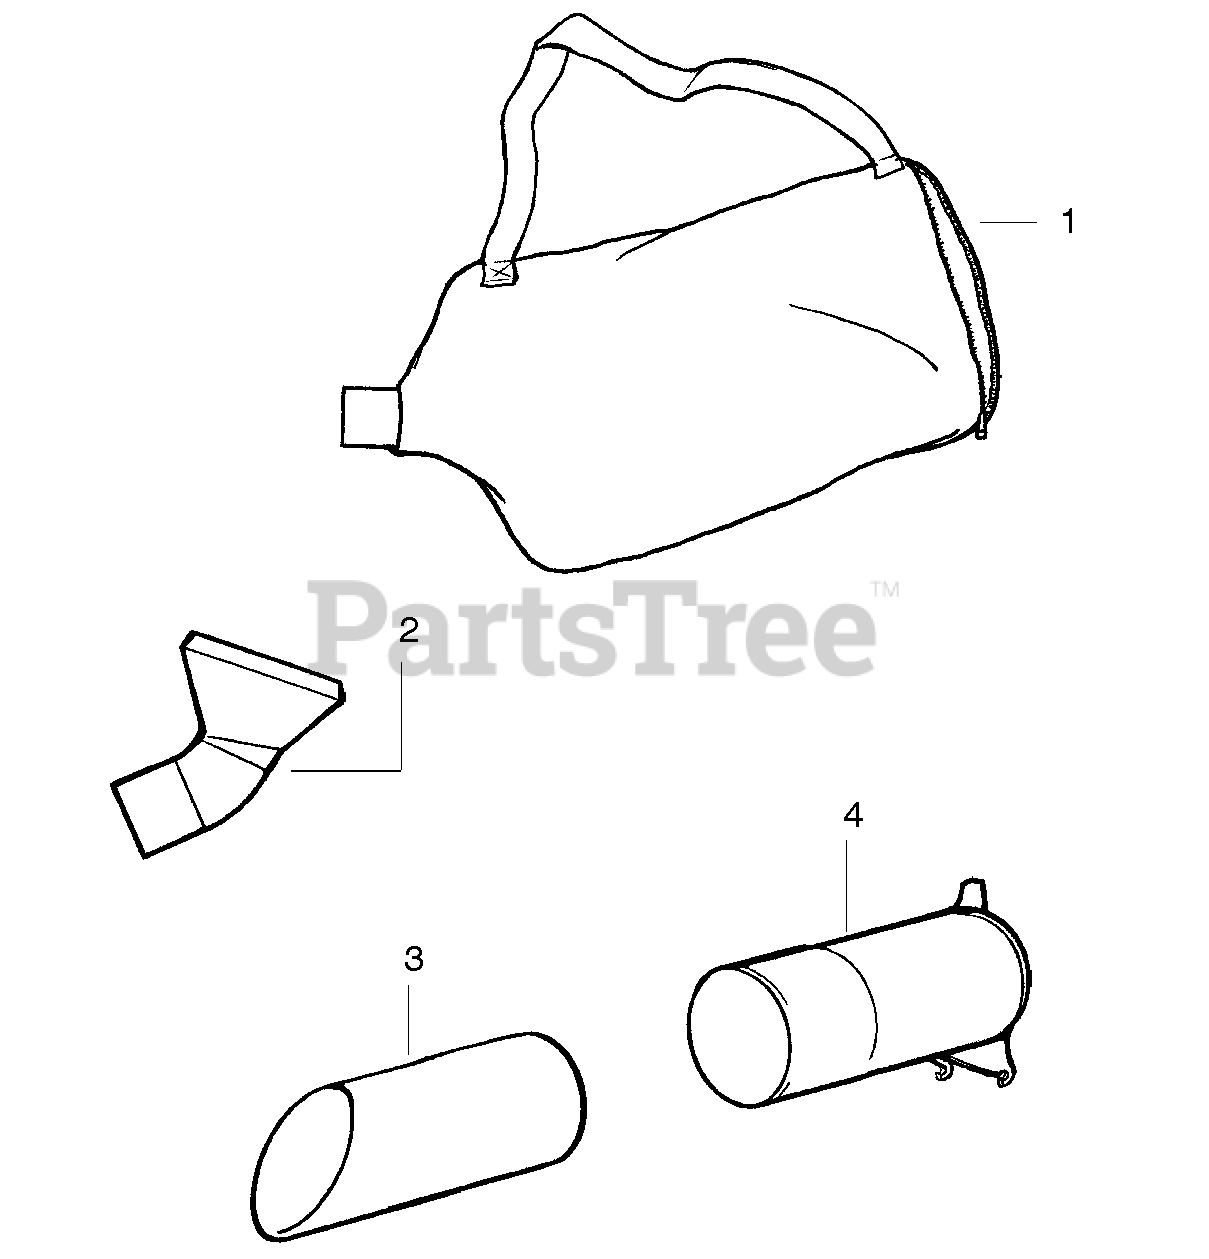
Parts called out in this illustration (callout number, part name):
1	Assy-Vac. Bag w/strap
2	Tube-Elbow Vac
3	Tube-Lower Vac
4	Tube-Upper Vac
